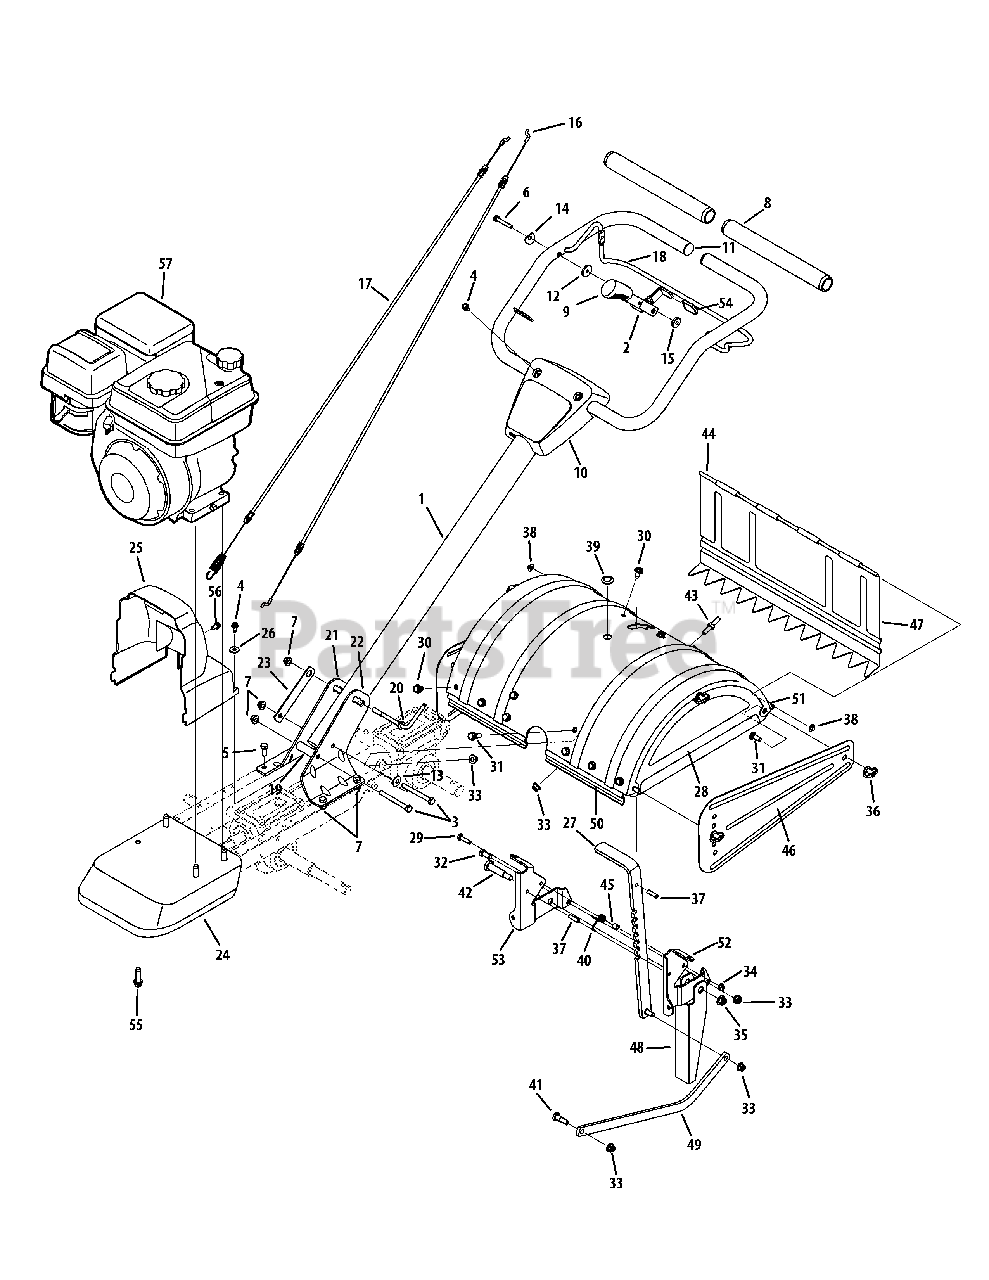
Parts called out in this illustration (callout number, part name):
1	Upper Handle Assembly
2	Reverse Handle Assembly
3	Hex Screw, 5/16-18 x 3.00
4	Hex Washer Screw, 1/4-20 x 0.500
5	Hex Washer Screw, 5/16-18 x .875
6	Hex Lock Screw, 1/4-20 x 1.62
7	Flange Lock Nut, 5/16-18
8	Foam Grip, .970 x 11.0
9	Selector Handle
10	Handle Cover, 400
11	End Plug
12	Flat Washer, .265 x .938 x .120
13	Bell Washer, .340 x .872 x .060
14	Saddle Washer, .320 x .93 x .060
15	Shoulder Spacer, .375 x .165
16	Reverse Cable
17	Forward Cable
18	Bail
19	Spacer, .322 x .625 x 2.00
20	Handle Adjustment Crank
21	RH Handle Bracket
22	LH Handle Bracket
23	400 Nut Retainer Bracket
24	Front Bumper
25	Belt Cover
26	Flat Washer, .28 x .74 x .063
27	Depth Adjustment Bracket
28	End Cover Assembly
29	Hex Screw, 1/4-20 x 1.00
30	Hex Washer Screw, 5/16-18 x 0.625
31	Hex Washer Screw, 5/16-18 x .875
32	Hex Screw, 5/16-18 x .75
33	Flange Lock Nut, 5/16-18
34	Flange Lock Nut, 1/4-20
35	Flange Lock Nut, 3/8-16
36	Wing Nut w/ Bell Washer, 5/16-18
37	Spring Pin, 1/4 x 1.00
38	Cap Speed Nut, 1/4
39	Deck Hole Plug
40	Torsion Spring
41	Shoulder Screw, 5/16-18 x .405 x .345
42	Shoulder Screw, .498 x 1.635
43	Hex Screw, 5/16-18 x .75
44	Tiller Flap Rod
45	Round Spacer, .370 x .260 x .410
46	Side Shield
47	Rear Tine Shield
48	Stop Reverse Arm
49	Depth Drag Bar
50	Tine Shield Mount Bracket
51	Tine Shield
52	LH Tail Bracket
53	RH Tail Bracket
54	Reverse Handle Grip
55	Hex Washer Screw, 3/8-16 x 1.250
56	Hex Washer Screw, 3/8-16 x 1.250
57	Replacement Engine
